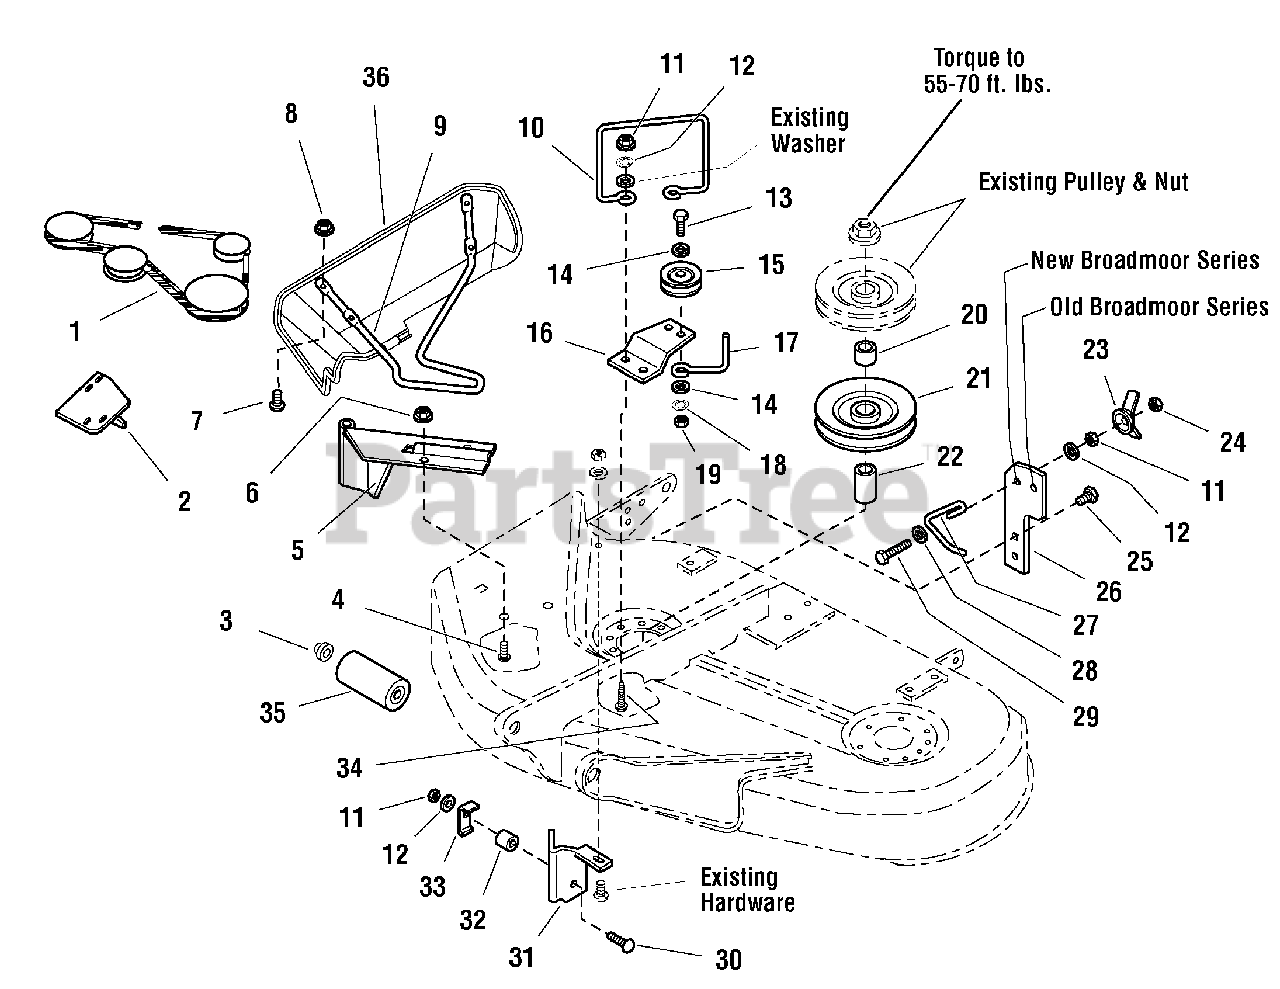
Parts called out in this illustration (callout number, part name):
1	V-BELT, Cog, 47-7/8
2	BRACKET & PLATE ASSEMBLY
3	PAL NUT, 5/8
4	BOLT, Carriage, 5/16-18 x 3/4
5	PIVOT ASSEMBLY
6	NUT, Hex, Flange Whizlock, 5/16-18
7	CAPSCREW, Truss Head, #10-24 x 3/4
8	NUT, Nylock, #10-24
9	ROD, Deflector
10	BELT GUIDE, Turbo
11	NUT, Hex, 5/16-18
12	LOCKWASHER, 5/16
13	CAPSCREW, Hex Head, 3/8-16 x 1-1/4
14	WASHER, Flat, 3/8
15	PULLEY, Idler
16	BRACKET, Idler
17	BELT STOP
18	LOCKWASHER, 3/8
19	NUT, Hex, 3/8-16
20	SPACER, Short
21	PULLEY ASSEMBLY
22	SPACER, Long
23	NUT, Wing, 5/16
24	NUT, Hex, Center Lock, 5/16-18
25	SCREW, Taptite, 5/16-18 x 1/2
26	BRACE
27	SPRING LATCH
28	WASHER, Flat
29	CAPSCREW, Hex Head, 5/16-18 x 2-1/2
30	BOLT, Carriage, 5/16-18 x 1-1/4
31	BRACKET ASSEMBLY
32	SPACER
33	BRACKET, "L"
34	CAPSCREW, Hex Head Taptite, 5/16-18 x 1-1/2
35	ROLLER
36	DEFLECTOR
